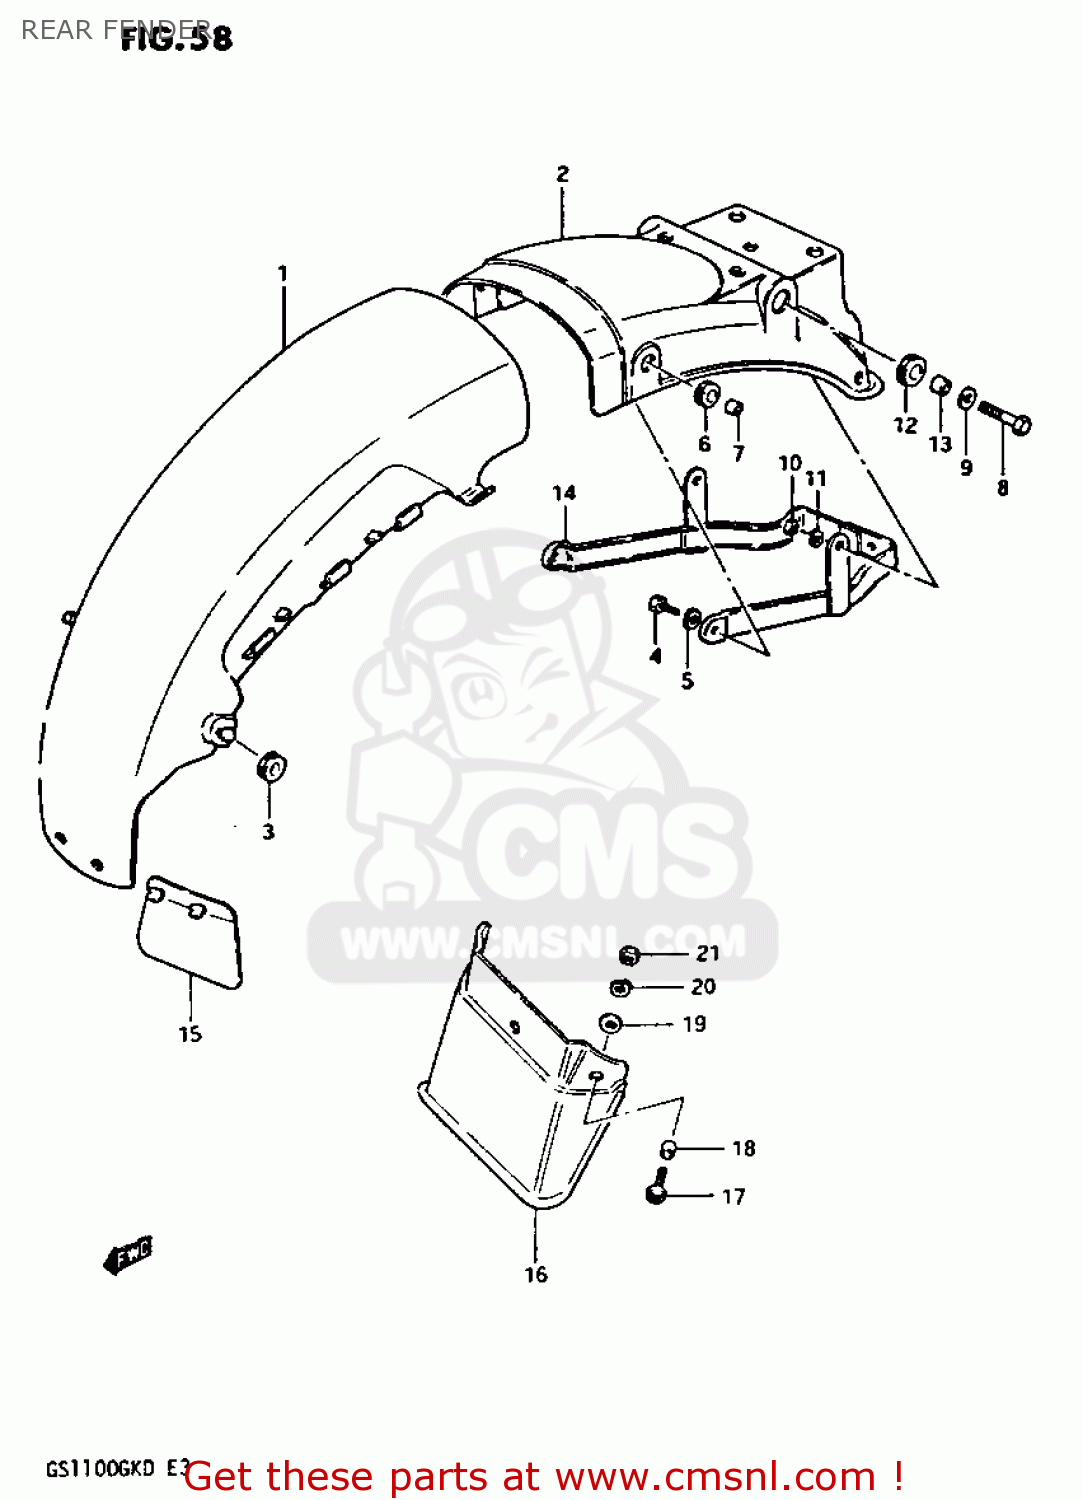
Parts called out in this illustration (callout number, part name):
1	BODY,RR FENDER FR
2	FENDER,REAR
3	CUSHION
4	BOLT
5	WASHER,LOCK
6	CUSHION
7	SPACER(6.1X9X7.5)
8	BOLT 8X40
9	WASHER
10	NUT
11	LOCK WASHER
12	CUSHION
13	SPACER (8.2X12X7.5)
14	REINFORCEMENT,REAR FENDER
15	GUIDE,RR FENDER MUD
16	EXTENSION,REAR FENDER
17	SCREW (6X15)
18	SPACER(6.2X8.3X5.7)
19	WASHER(6.5X18X1)
20	WASHER,LOCK
21	NUT
